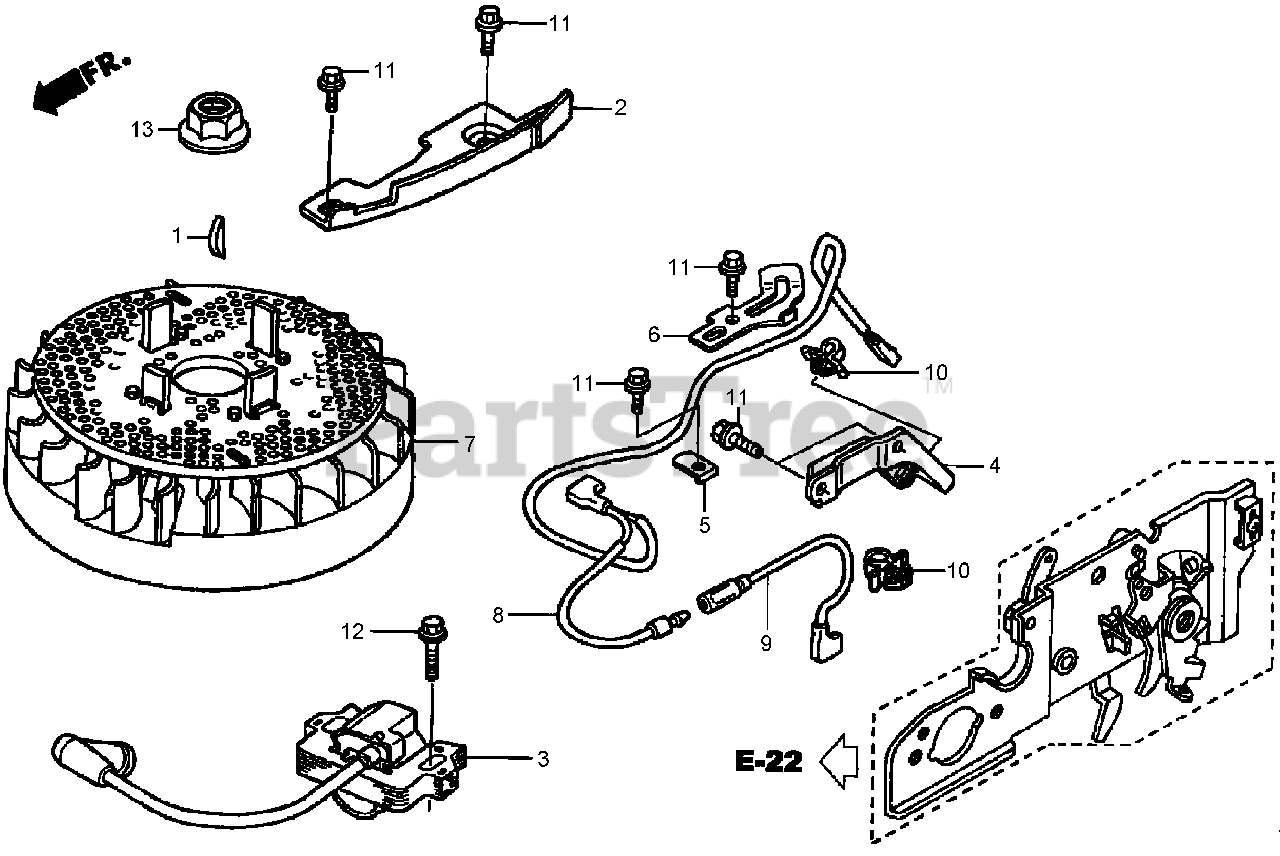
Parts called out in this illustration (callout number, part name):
1	KEY-WOODRUFF (25X18)
2	PLATE-SIDE
3	IGNITION COIL ASM
4	CLAMP-WIRE, STOP SWITCH
5	CLAMP-WIRE, STOP SWITCH
6	CLAMP-WIRE
7	FLYWHEEL ASM
8	WIRE-SWITCH, STOP
9	WIRE-SWITCH, STOP
10	HOLDER-WIRE
10	CLIP-CABLE (A)
11	BOLT-FLANGE (6X12) (CT200)
12	BOLT-FLANGE (6X20)
13	NUT (14MM)
